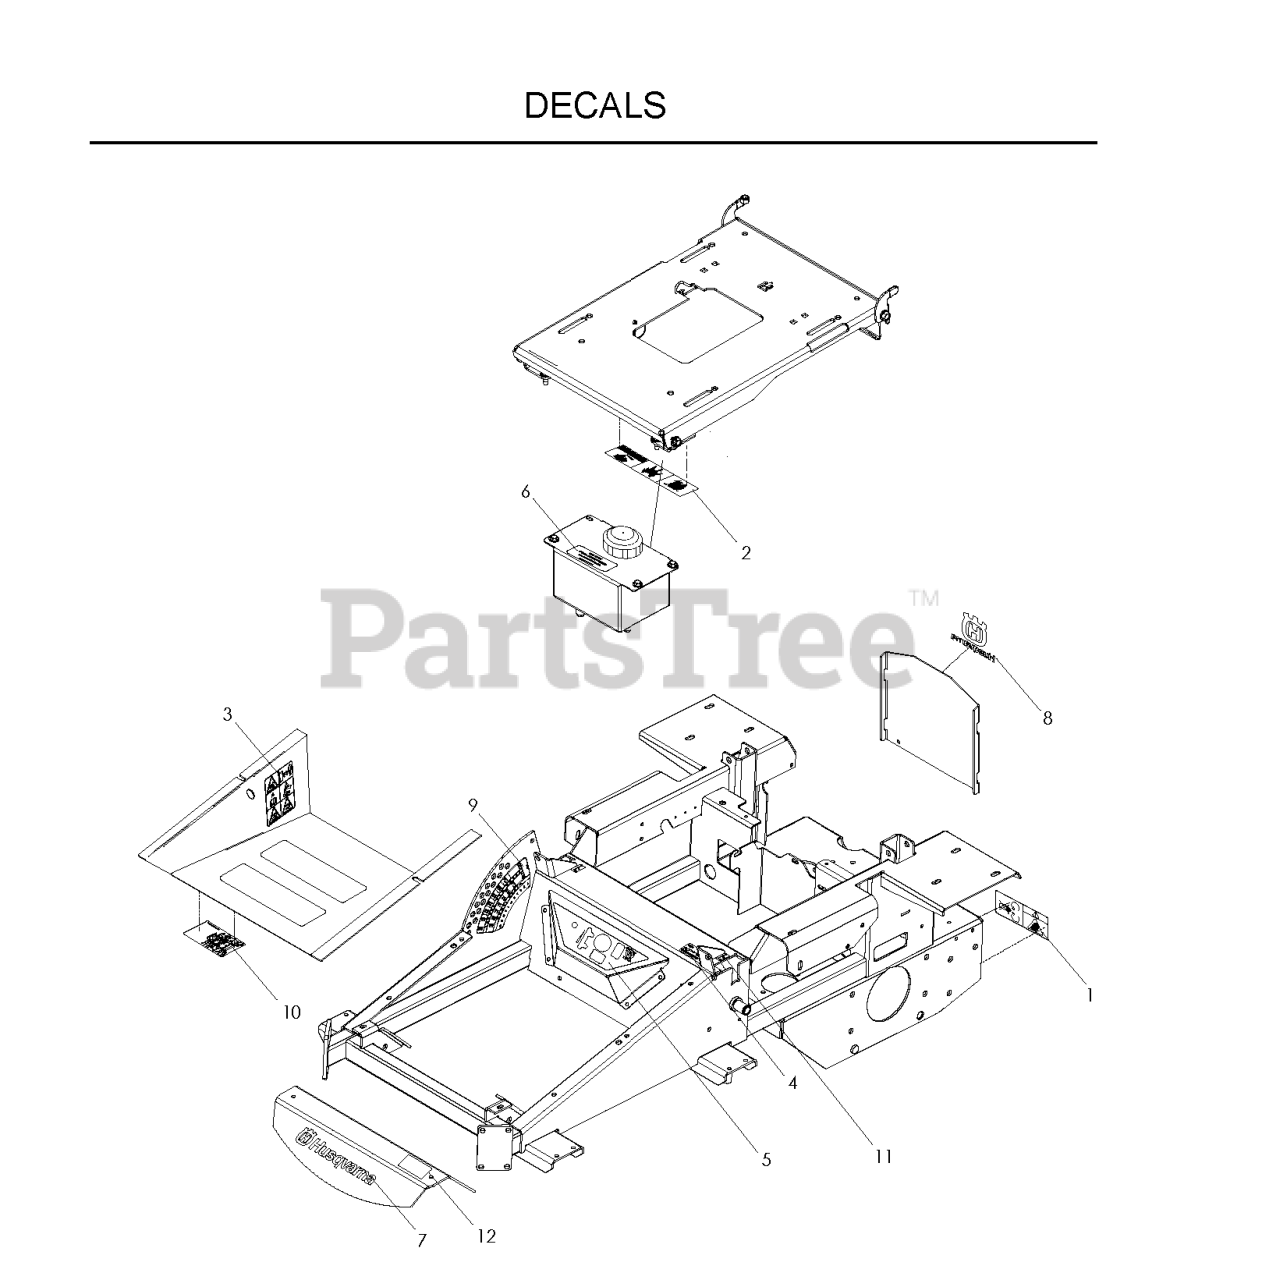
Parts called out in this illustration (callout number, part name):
1	DECAL, BELT DRIVE
2	EURO DECAL-BATTERY WARNIN6
3	DECAL, WARNING
4	DECAL, F.S.T.
5	DECAL, CONSOLE
6	DECAL, OIL TANK
7	DECAL, HUSQ 12" BLUE
8	DECAL, CROWN H 5-1/4 SILVER
9	DECAL, HEIGHT, IZE
10	SERVICE DECAL
11	DECAL, MOTION CONTROL
12	DECAL, IZ21
